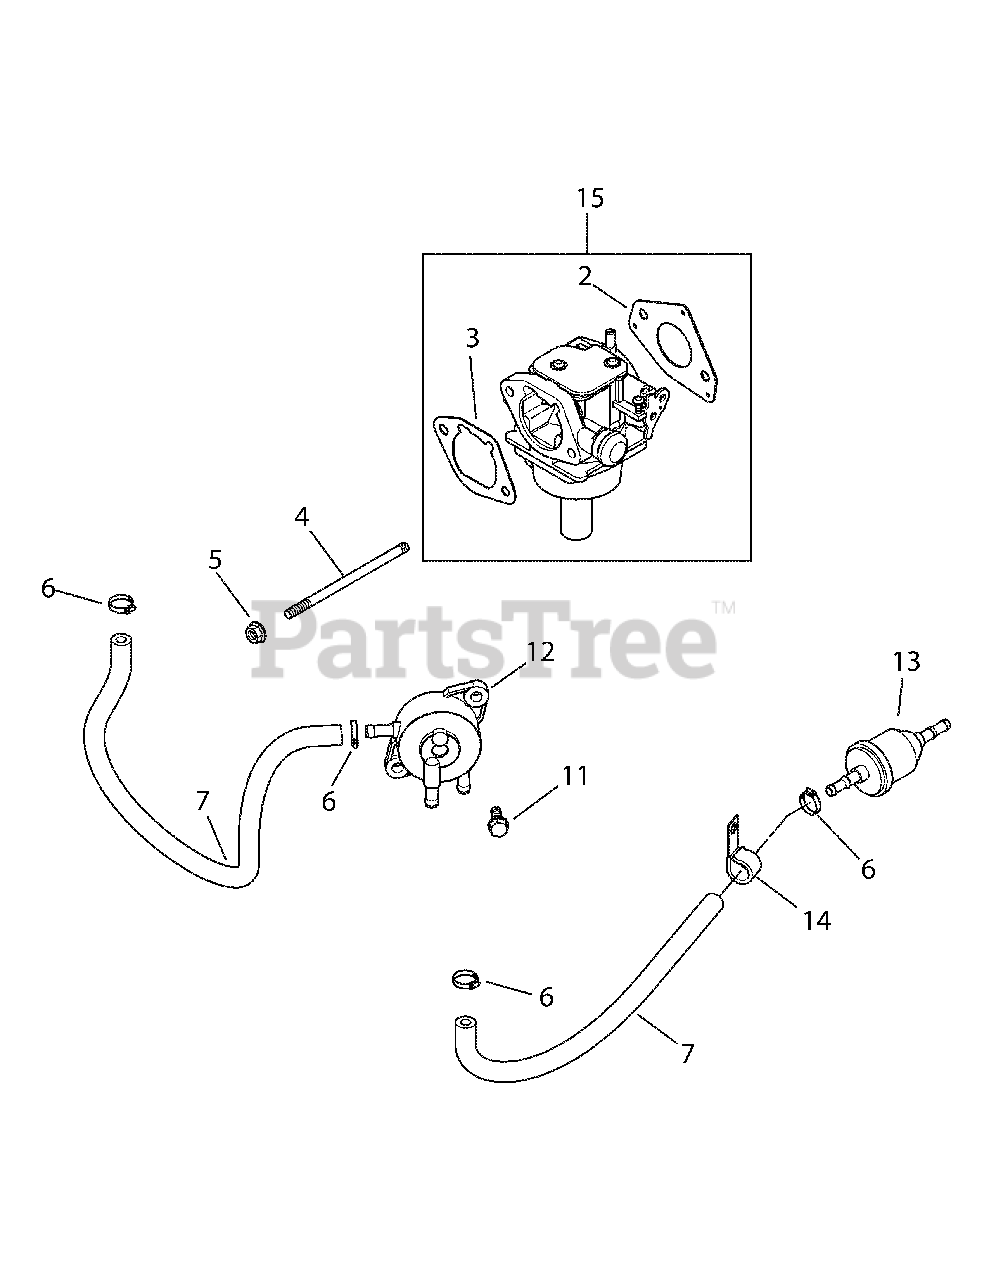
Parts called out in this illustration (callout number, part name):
2	Carburetor Gasket
3	Air Cleaner Base Gasket
4	Stud, M6 X 1.0 X 106
5	Flg. Nut, M6 X 1.0
6	Hose Clamp, 1/2
7	Fuel Line
11	Tap Screw, M6 X 1.7 X 18
15	Carburetor Assembly, 19mm KEIHIN (Inc.2 & 3)
